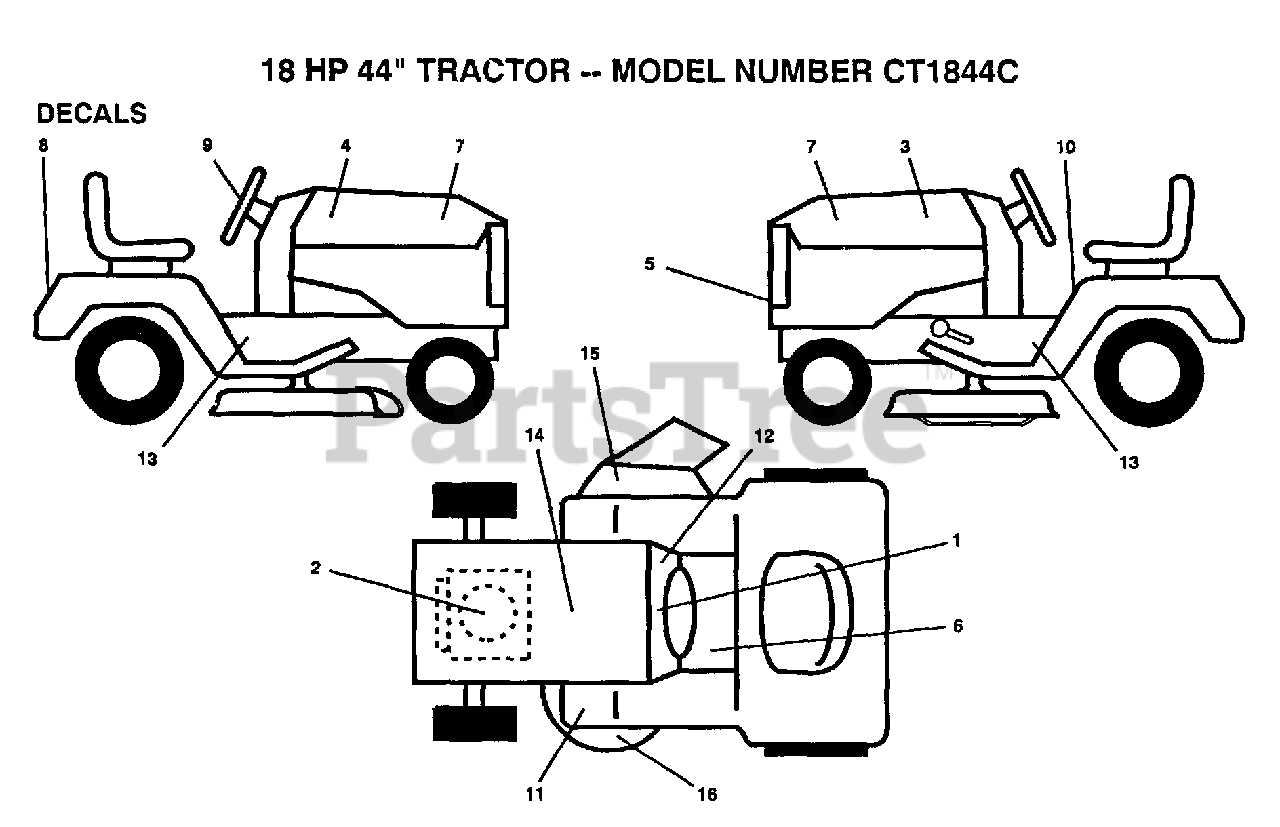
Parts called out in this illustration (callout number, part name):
2	DECAL.ENG.272559
5	GRILL DECAL
7	DECAL PANEL T
8	FENDER DECAL
9	"DECAL,STR WHL"
10	DECAL CAUTION
11	DECAL T
14	DECAL
15	DECAL WARNING
16	DECAL YT
